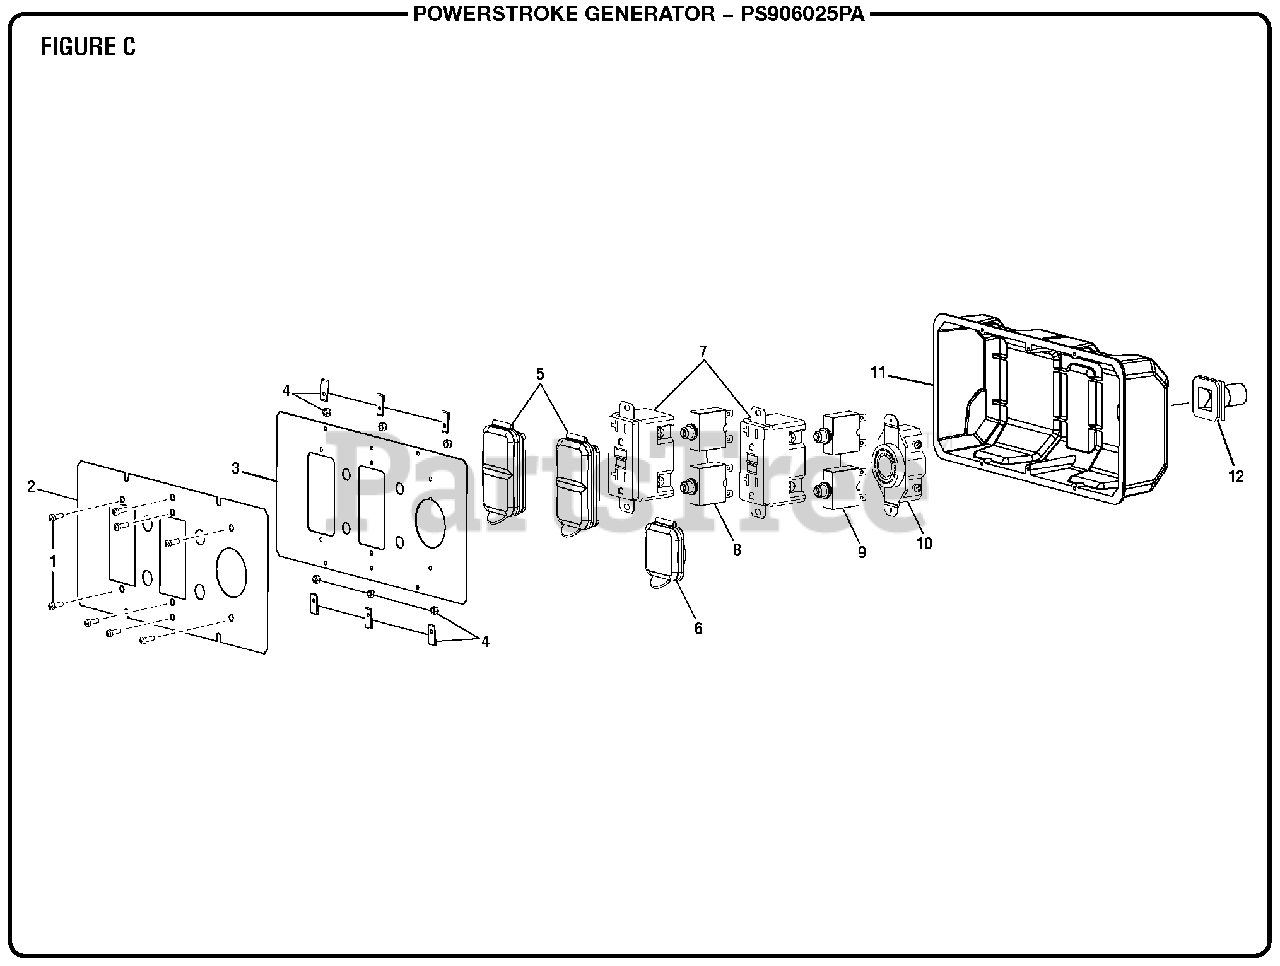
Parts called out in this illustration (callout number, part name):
1	Screw (6-20 x 3/8 in.)
2	Label (Power Outlet)
3	Front Panel
4	U-Clip Nut
4	Hex Nut (6-32)
5	Outlet Cover (120 Volt)
6	Outlet Cover (240 Volt)
7	Duplex GFCI Receptacle (120 Volt)
8	Circuit Breaker, 20 Amp
9	Circuit Breaker, 25 Amp
10	Twist Lock Receptacle (240 Volt)
11	Control Box (Back Panel)
12	Rubber Boot
